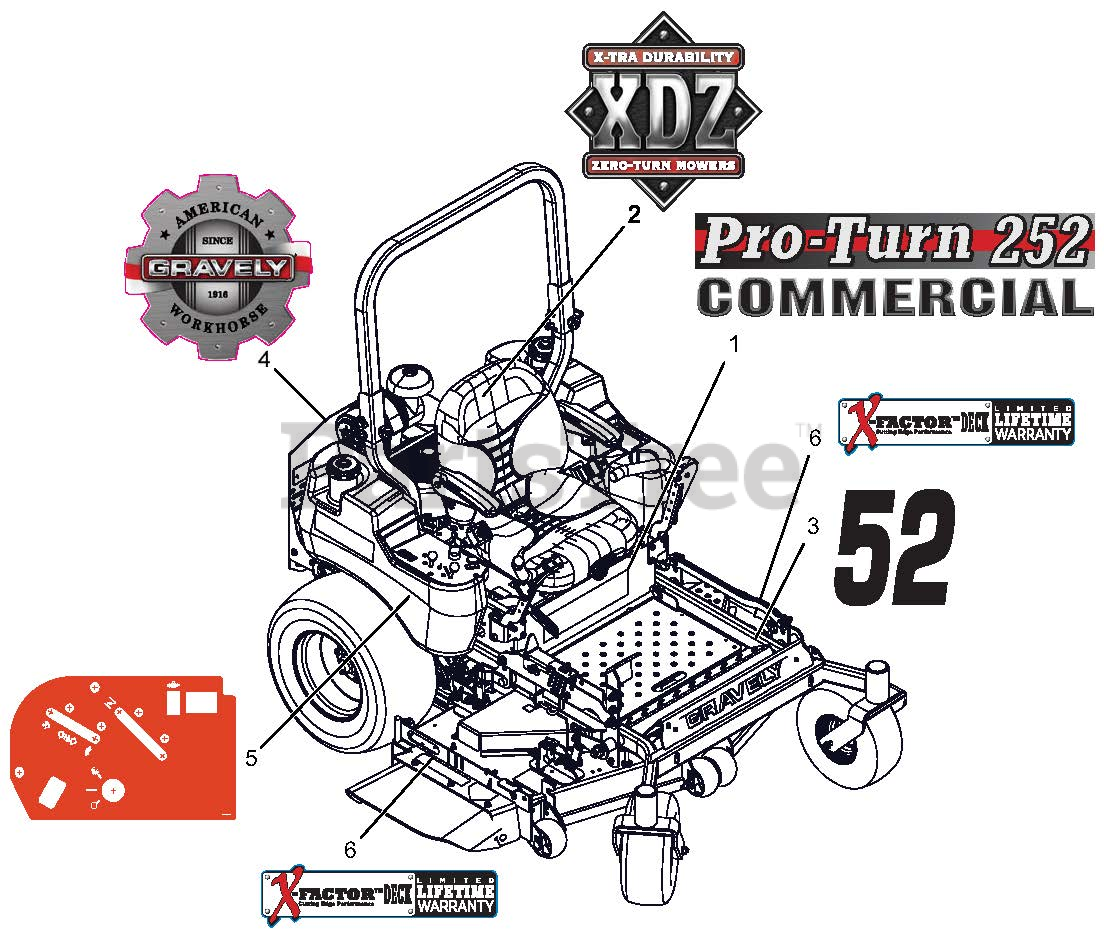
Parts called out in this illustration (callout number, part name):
1	DECAL, PROTURN 252
2	DECAL, XDZ
3	DECAL, 52"
4	DECAL, GRAVELY HERITAGE-LARGE
5	DECAL, CONTROL PANEL NON-EFI
6	DECAL, X-FACTOR DECK
